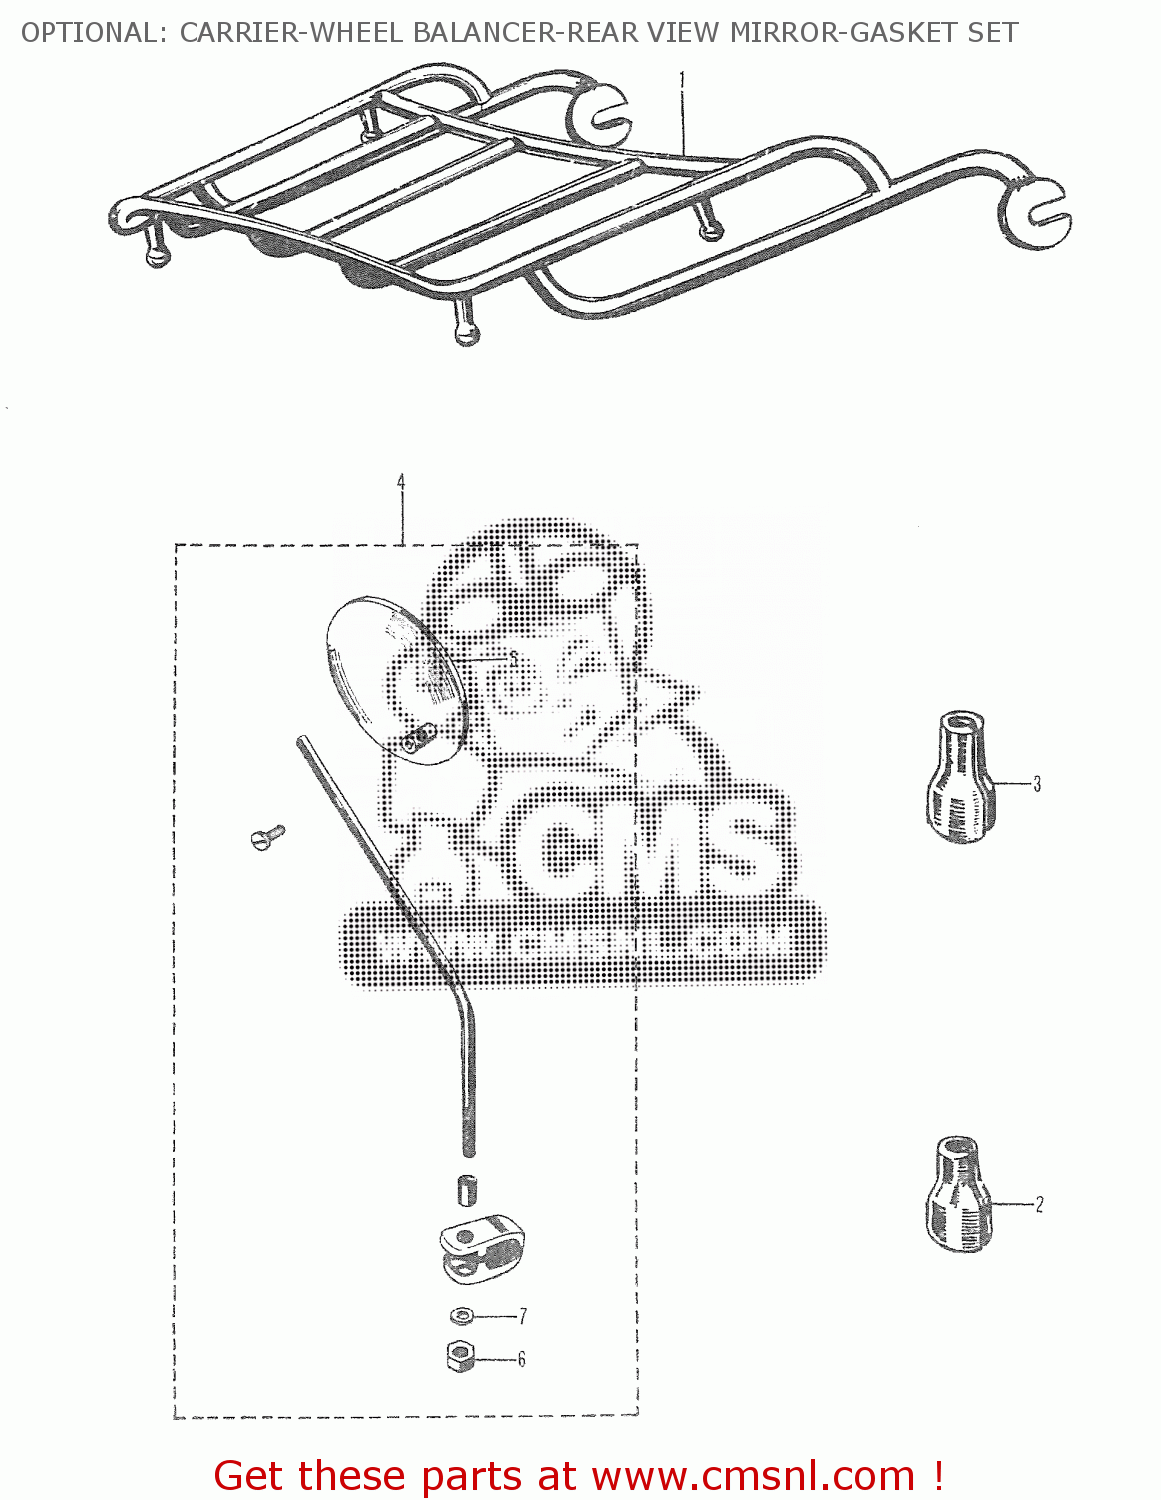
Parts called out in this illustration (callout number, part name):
1	CARRIER
2	BALANCER,WHEEL (B)
3	BALANCER,WHEEL (30G)
4	MIRROR ASSEMBLY,RIGHT
5	REAR VIEW MIRROR
6	SMALL HEXAGON NUT
7	GASKET
